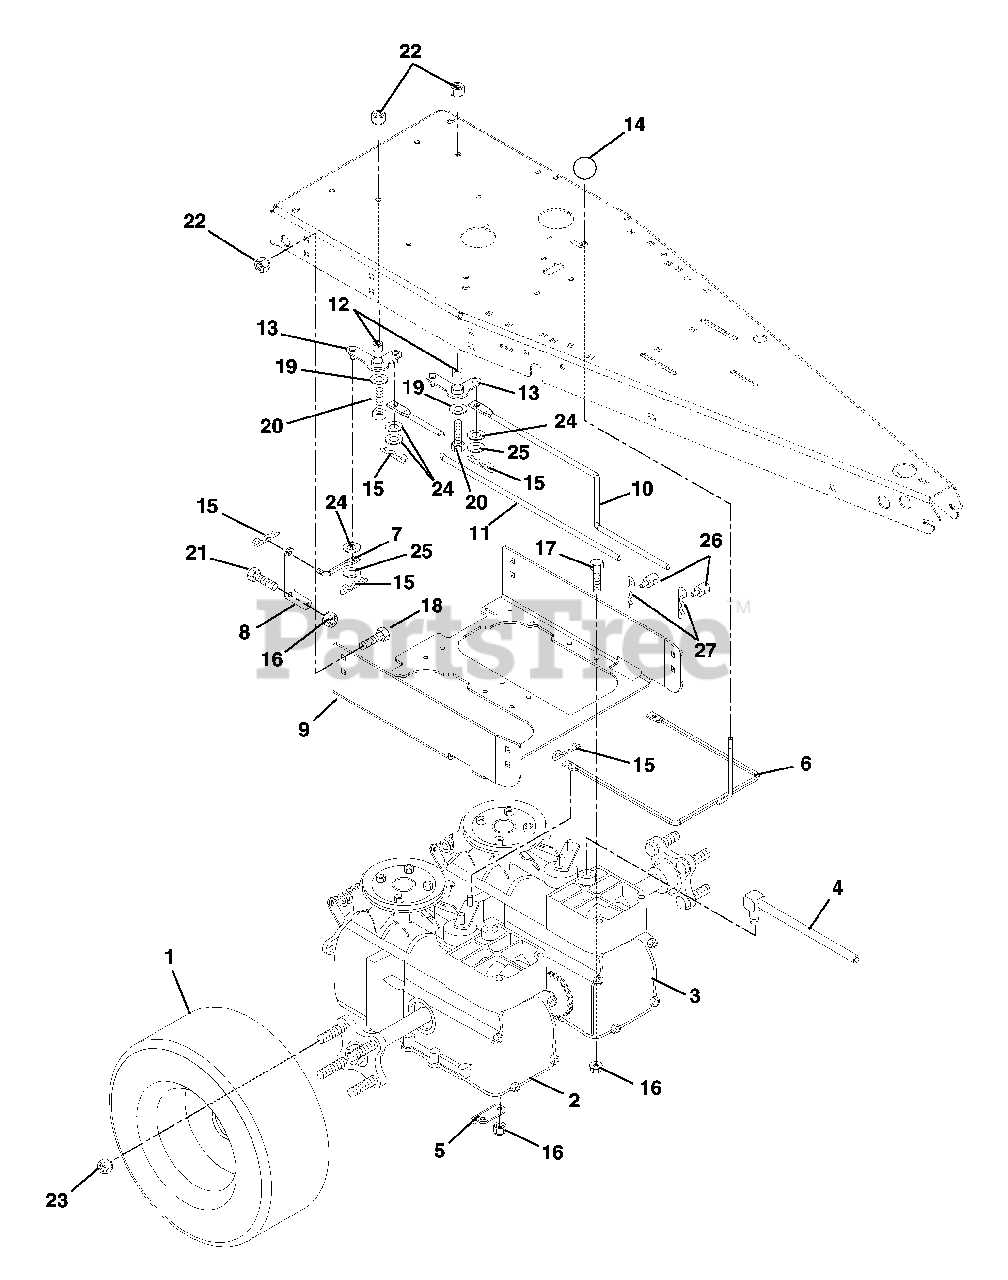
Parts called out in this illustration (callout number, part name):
1	Tire/Wheel Assembly 18 x 6.50-8 2 Ply (032)
1	Tire/Wheel Assembly 18 x 6.50-8 2 Ply (030)
2	Transaxle, Hydro Gear
3	Transaxle, Hydro Gear
4	Assembly, Breather
5	Bracket, Axle Support
6	Weldment, Dump Rod
7	Rod, Bell Crank
9	Cradle, Transmission
10	Rod, Steering Left Hand
11	Rod, Steering Right Hand
12	Bushing
13	Weldment, Bell Crank
15	Pin, Hair
16	Nut, Locking Top Flange .31-18
17	Bolt, Hex .31-18 x 2.50 Grade 5
18	Bolt, Round Head Square Neck .38-16 x .75 Grade 5
19	Washer, Flat Steel .38 x .875 x .083
20	Bolt, Hex .38-16 x 1.25 Grade 5
21	Bolt, Hex .31-18 x .75 Grade 5
22	Nut, Locking Top Flange .38-16
23	Nut, Lug .50-20
24	Washer, Flat Steel .38 x .87 x .179
25	Washer, Flat Steel .39 x .75 x .125
26	Trunnion, Brake
27	Pin, Hair
